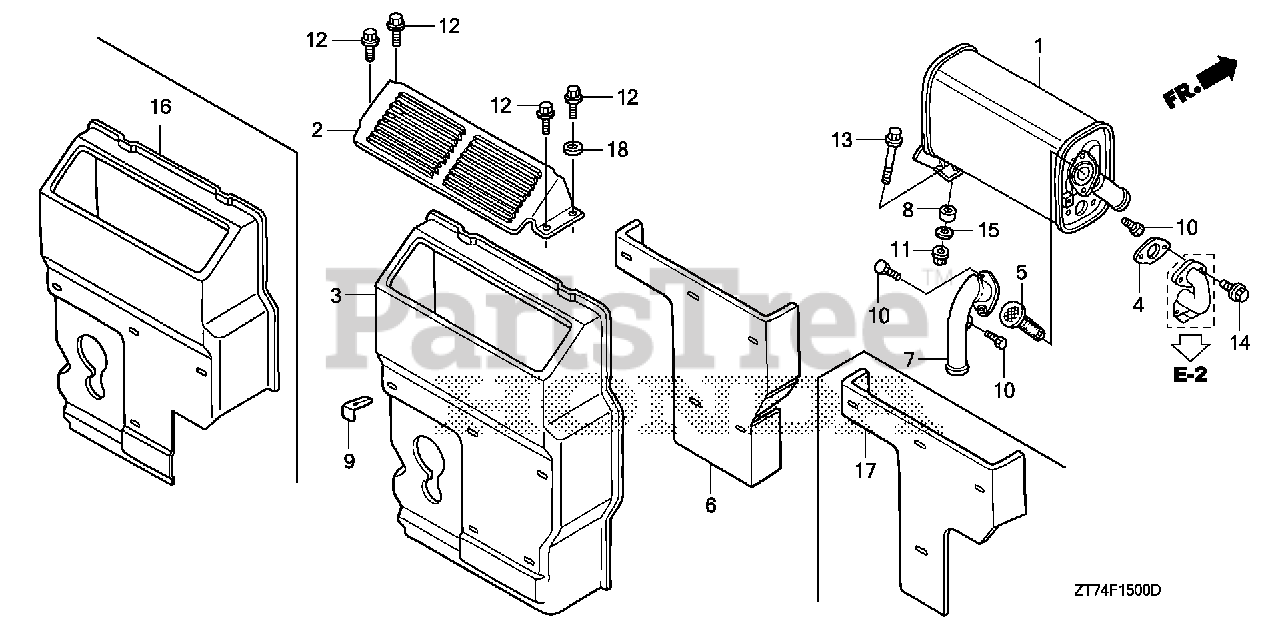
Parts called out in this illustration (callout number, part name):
1	MUFFLER
2	PROTECTOR, MUFFLER (UPPER)
4	GASKET, EX. PIPE
5	ARRESTER, SPARK
7	PIPE, EX. TAIL
8	WASHER, WHEEL (6MM)
9	CLIP, INSULATOR BIND
10	BOLT, SLOT (5X8)
11	NUT, FLANGE (6MM)
12	BOLT, FLANGE (6X10)
13	BOLT, FLANGE (6X30)
14	BOLT, FLANGE (8X20) Use up to Engine SN 1609606.
15	WASHER, PLAIN (6MM)
16	PROTECTOR, MUFFLER (LOWER)
17	INSULATOR, MUFFLER PROTECTOR
